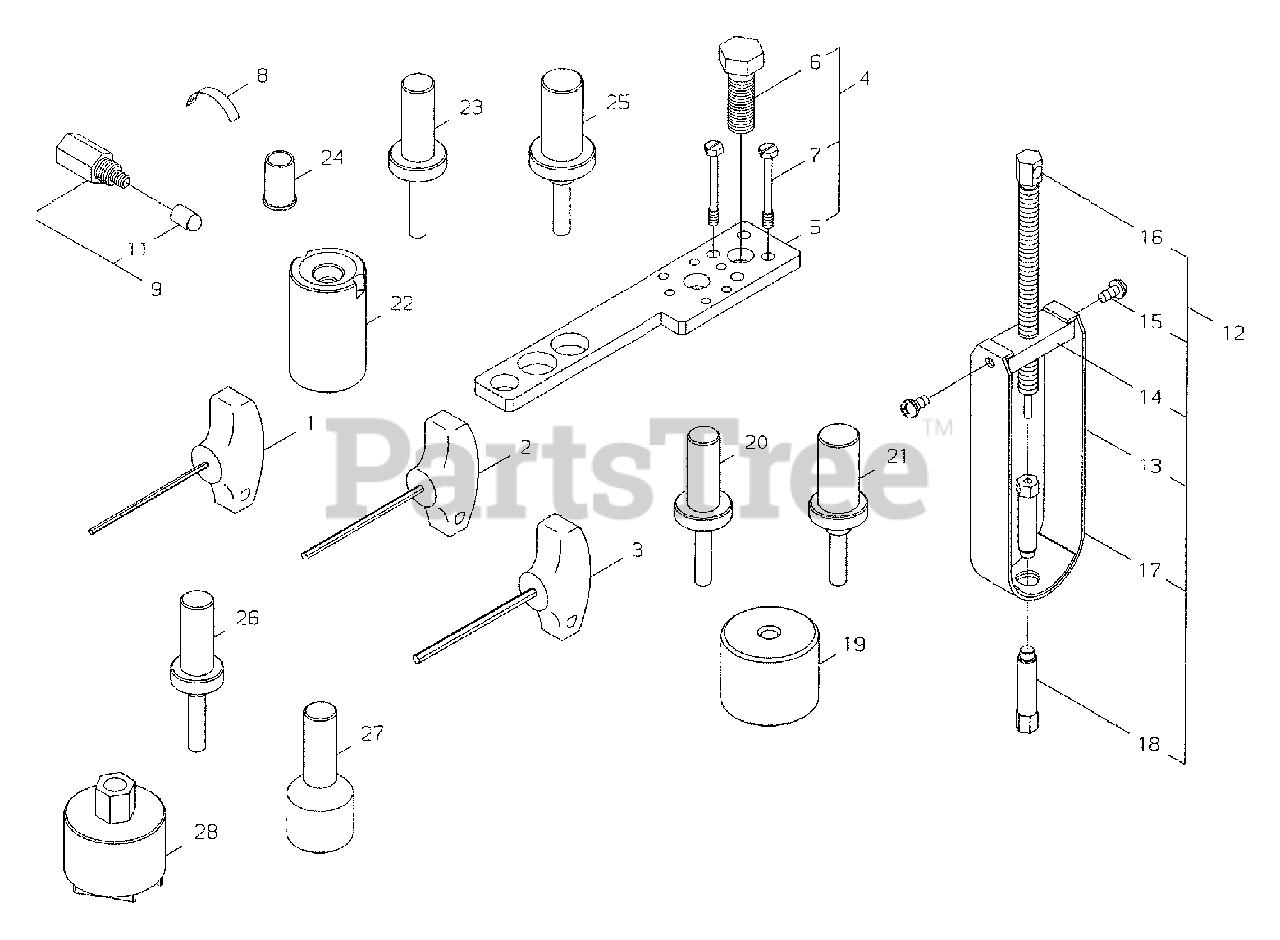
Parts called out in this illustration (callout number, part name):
1	T-WRENCH - 3 MM
2	T-WRENCH - 4 MM
3	T-WRENCH - 5 MM
4	PULLER ASSY
5	LEVER
6	BOLT, CENTER
8	GAUGE, GAP
9	STOPPER ASSY
11	CAP
12	PULLER TOOL KIT
13	PULLER
14	BOSS
16	BOLT
17	PIN ADAPTOR
18	PIN, GUIDE
19	HOLDER M
20	SEAL, OIL
21	ROD - 6202
23	SEAL, OIL
24	SEAL, OIL
25	ROD - 6203
